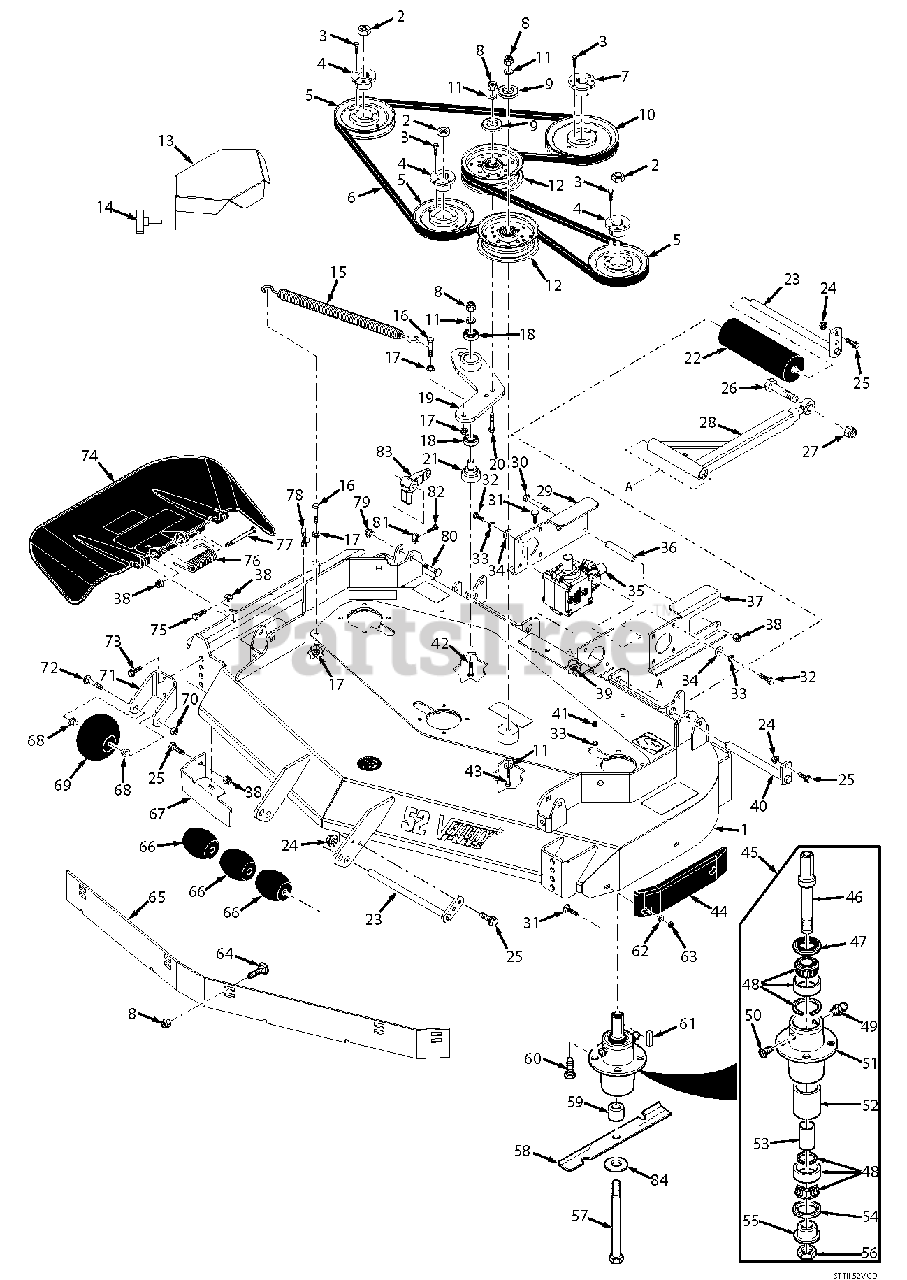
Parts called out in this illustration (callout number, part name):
1	Cutter Deck w/Decals - 52V
2	Nut, 5/8-11 UNC
3	Bolt, Hex Head 1/4-20 x 1"
4	Tapered Hub, 1-1/8" Bore
5	Pulley, 5.75 O.D.
6	Belt, Cutter Deck Drive
7	Tapered Hub, 1" Bore
8	Nut, Elastic Stop 3/8-16
9	Dust Shield
10	Pulley, 6.95 O.D.
11	Flatwasher, 3-8/.391 x .938 x .105 HD
12	Pulley, Idler
13	Belt Cover
14	Knob w/Stud
15	Spring
16	Bolt, Hex Head 3/8-16 x 1-1/2"
17	Nut, Serrated Flange 3/8-16
18	Bearing
19	Idler Arm Weldment
20	Bolt, Hex Head 3/8-16 x 2-3/4"
21	Pivot, Idler
22	Guide Roller
23	Roller Shaft
24	Nut, Serrated Flange 5/16-18
25	Bolt, Hex Head 5/16-18 x 1"
26	Bolt, Hex Head 5/8-11 x 4-1/2"
27	Nut, Elastic Stop 5/8-11
28	Pusharm Assy., LH & RH
29	Mounting Plate
30	Bolt, Hex Head 5/16-18 x 4-3/4"
31	Bolt, Carriage 5/16-18 x 3/4"
32	Bolt, Hex Head 5/16-18 x 1"
33	Lockwasher, 5/16"
34	Flatwasher, 5/16-.375 x .875 x .083
35	Gearbox
36	Spacer
37	Mounting Plate
38	Nut, Elastic Stop 5/16-18
39	Nut, Serrated Flange 5/16-18
40	Shaft Weldment, Pusharm
41	Nut, Elastic Stop 5/16-18
42	Bolt, Hex Head 3/8-16 x 3"
43	Bolt, Hex Head 3/8-16 x 3-3/4"
44	Pad, Deck Wear
45	Spindle Assembly
46	Shaft, Spindle
47	Seal, Top
48	Bearing Assembly
49	Grease Fitting
50	Relief Fitting, Tapered Spindle
51	Spindle Housing
52	Spacer, Outside
53	Spacer, Inside
54	Seal Bottom
55	Spindle Bushing, Bottom
56	Nut, Special 1-1/16 - 18
57	Bolt, Hex Head 5/8-11 x 9-1/2"
58	Cutter Blade, 18"
59	Spacer, Spindle Bottom
60	Bolt, 5/16-18 x 1-3/4"
61	Key, 1/4 x 1/4 x 2"
62	Flatwasher, 5/16-.344 x .688 x .065
63	Nut, Center Lock 5/16-18
64	Bolt, Carriage 3/8-16 x 1"
65	Baffle, Custom Cut - 52V
66	Wheel, Anti-Scalp
67	Baffle, Turbo
68	Bushing, .376 I.D. Oilite
69	Anti-Scalp Wheel
70	Nut, Center Lock 3/8-16
71	Bracket, Anti-Scalp
72	Bolt, Carriage 3/8-16 x 4"
73	Bolt, Hex Head Serrated Flange 3/8-16 x 1"
74	Discharge Chute Assy.
75	Bolt, Hex Head 5/16-18 x 1-3/4"
76	Spring, Discharge Chute
77	Bolt, Hex Head 5/16-18 x 4-3/4"
78	U-Nut, 3/8-16
79	Nut, Elastic Stop 7/16-14
80	Bolt, Carriage 7/16-14 x 2-1/4"
81	U-Nut, 3/8-16 (short)
82	Bolt, Hex Head 3/8-16 x 2" Special
83	Lever, Deck Level
84	Flatwasher, 5/8-.688 x 1.75 x .134 HD
